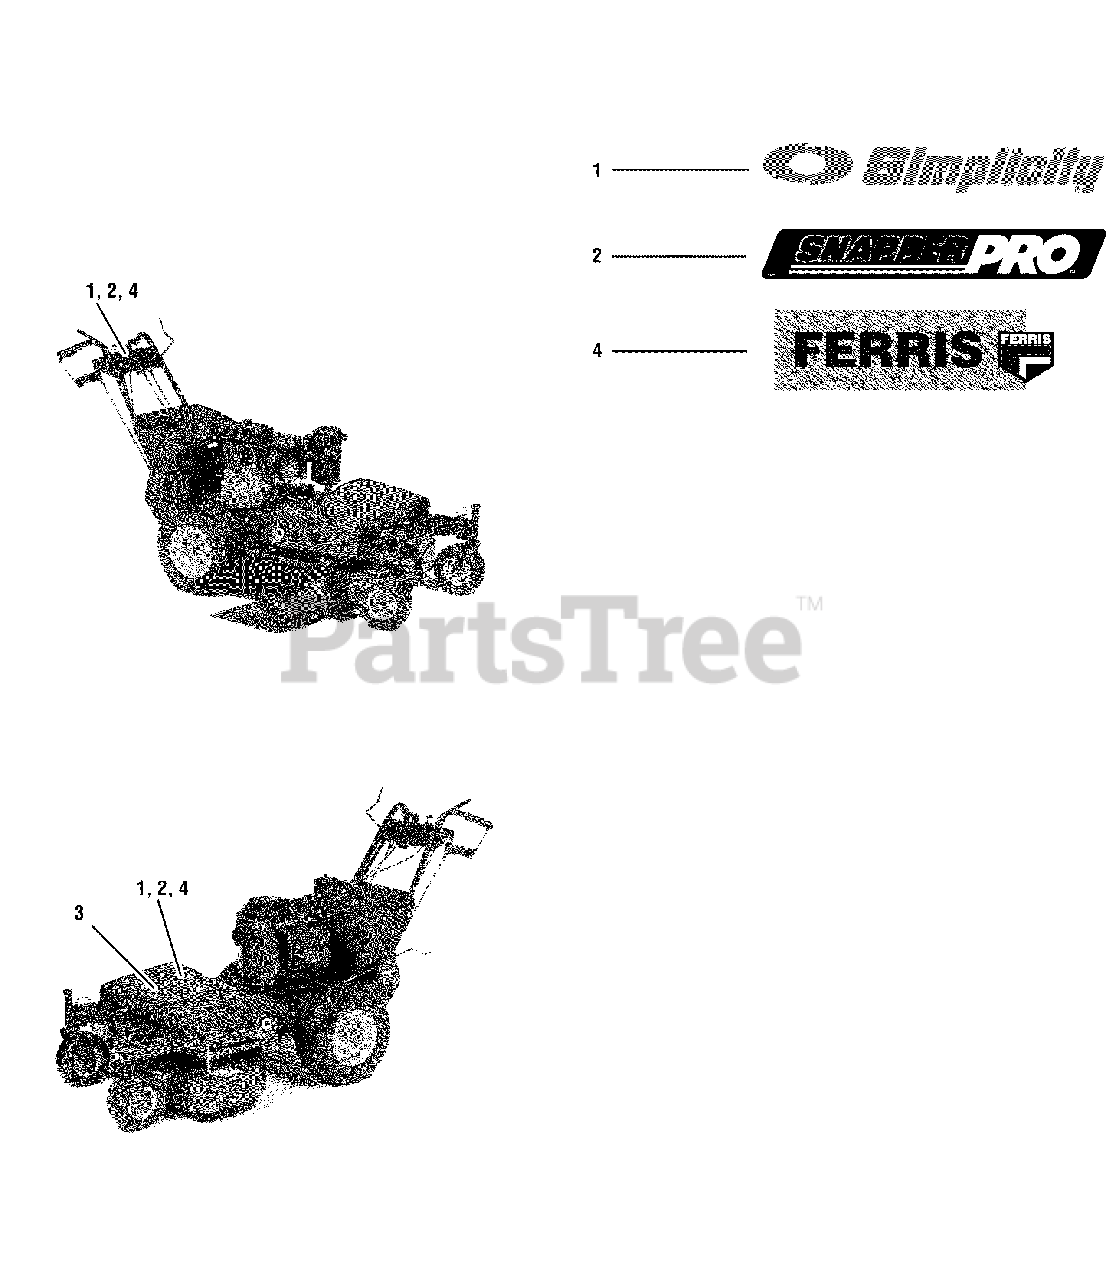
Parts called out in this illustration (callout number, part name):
1	DECAL, SIMPLICITY LOGO GV3079178
2	DECAL, SNAPPER PRO
4	DECAL, FERRIS TEXT & LOGO
